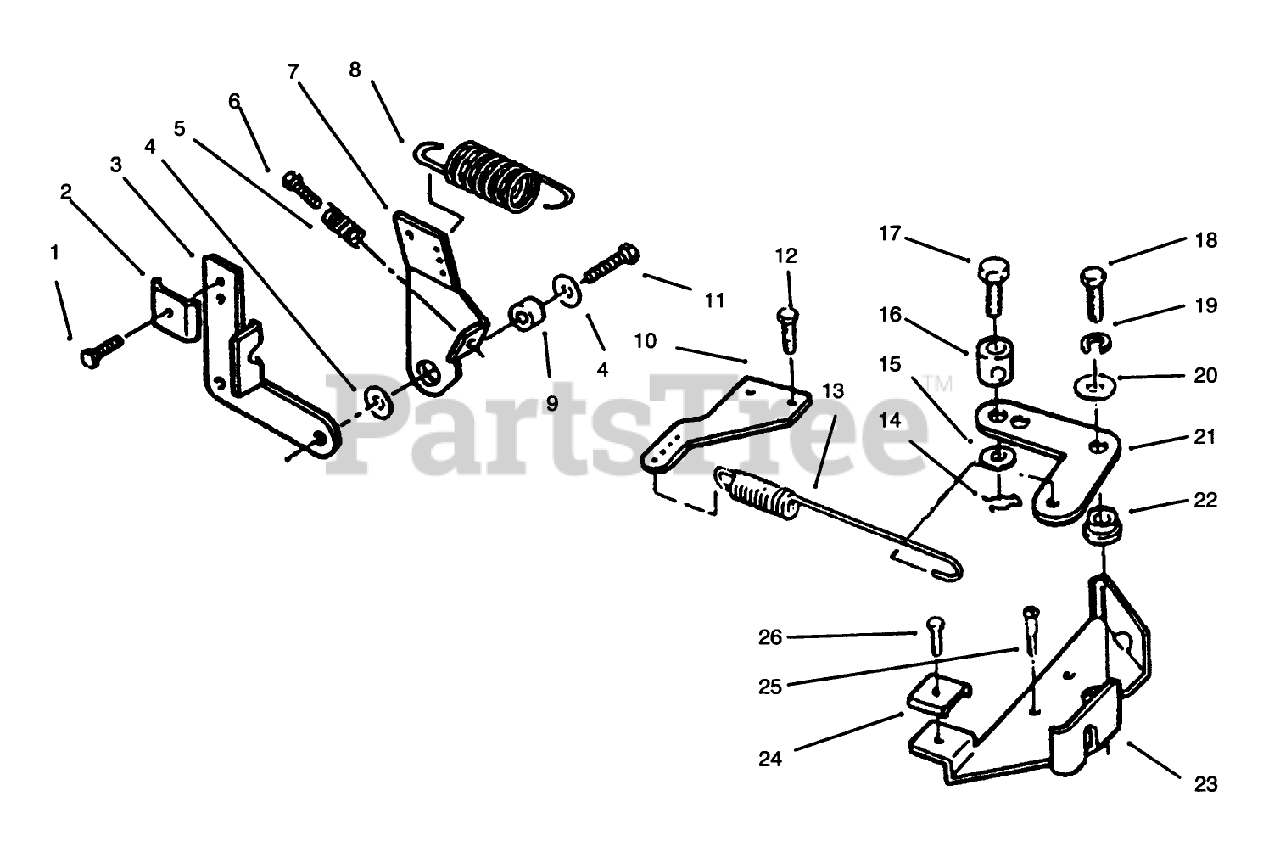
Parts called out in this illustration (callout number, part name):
1	SCREW-TAPPING
4	WASHER-FLAT
5	SCREW-TAP
6	SPRING
9	BUSHING
12	SCREW-TAPPING PAN HD
14	PIN-COTTER
16	BUSHING
17	SCREW
19	WASHER-LOCK, SPRING
20	WASHER-FLAT
23	BRKT-GOVERNOR CONTRL
25	SCREW-HWH
26	HEX HD CAP SCREW
